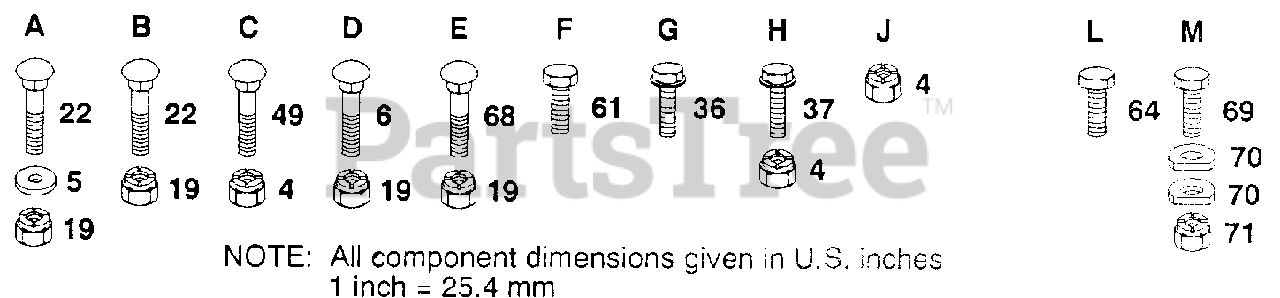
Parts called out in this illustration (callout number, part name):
5	WASHER M
6	BOLT
22	BOLT
36	SCREW
37	SCREW
49	BOLT
61	BOLT
64	BOLT.3/8-14X1.25
69	BOLT LT
70	WASHER T
